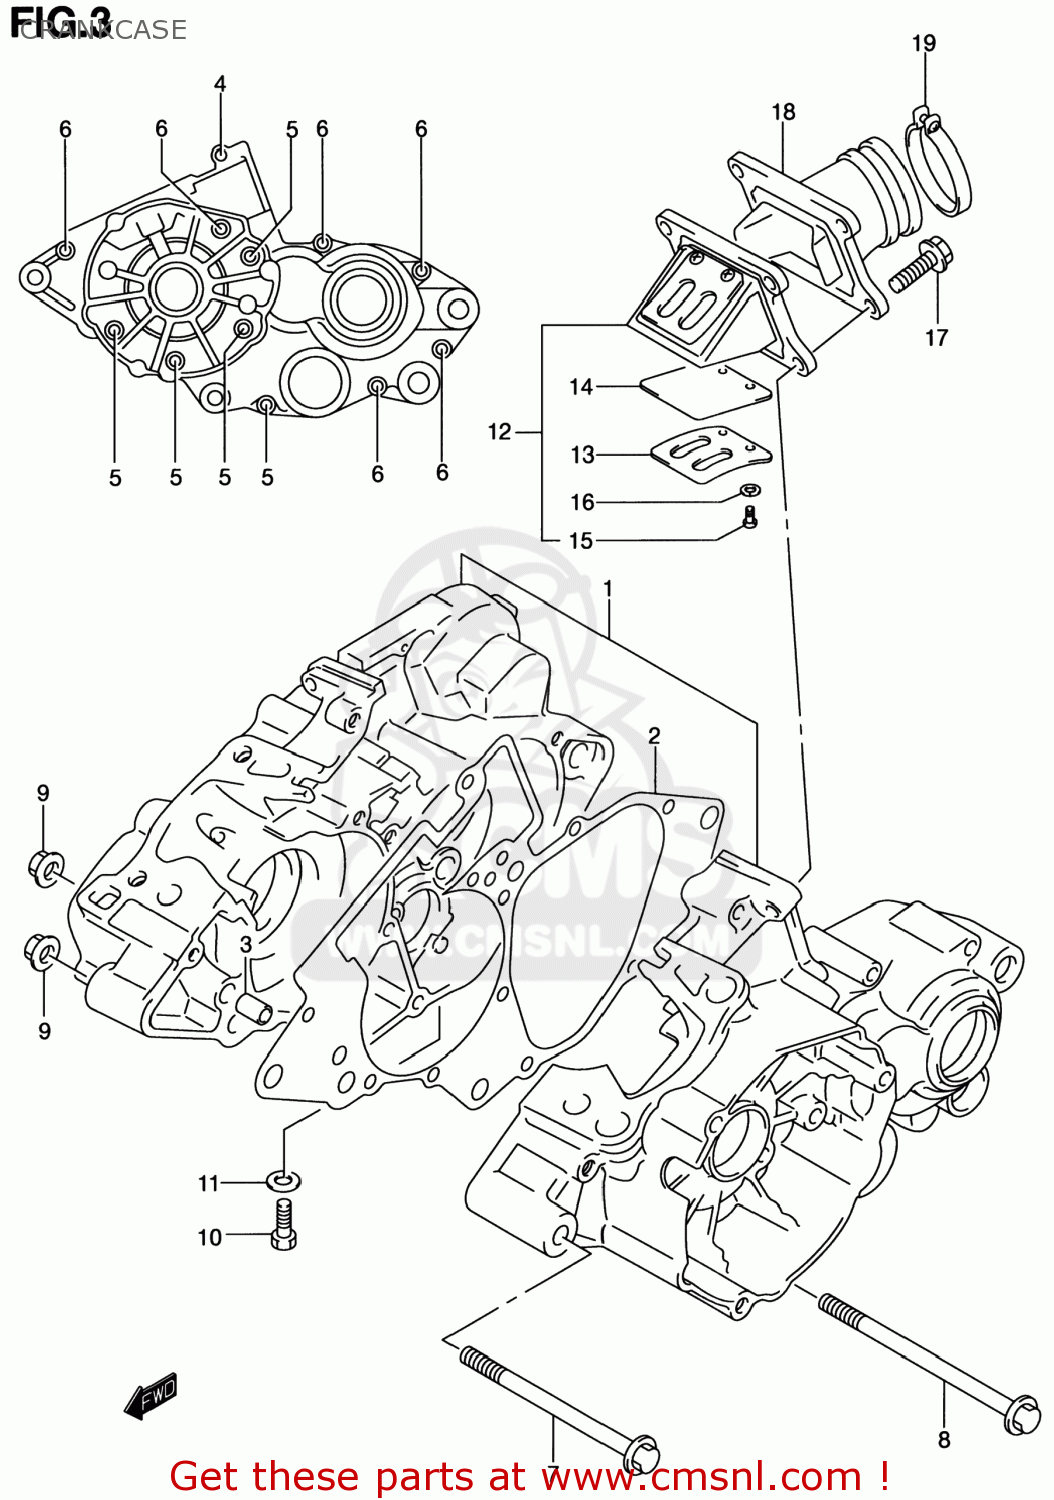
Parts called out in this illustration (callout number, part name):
1	CRANKCASE SET
2	GASKET,CRANKCASE (NAS)
3	PIN
4	BOLT
5	BOLT
6	BOLT
7	BOLT 8X92
8	BOLT(8X102)
9	NUT
10	BOLT
11	GASKET(8.2X14X1) (NAS)
12	VALVE ASSY,REED
13	STOPPER,REED VALVE
14	VALVE,REED
15	SCREW
16	WASHER,LOCK
17	SCREW
18	PIPE,INTAKE
19	CLAMP
